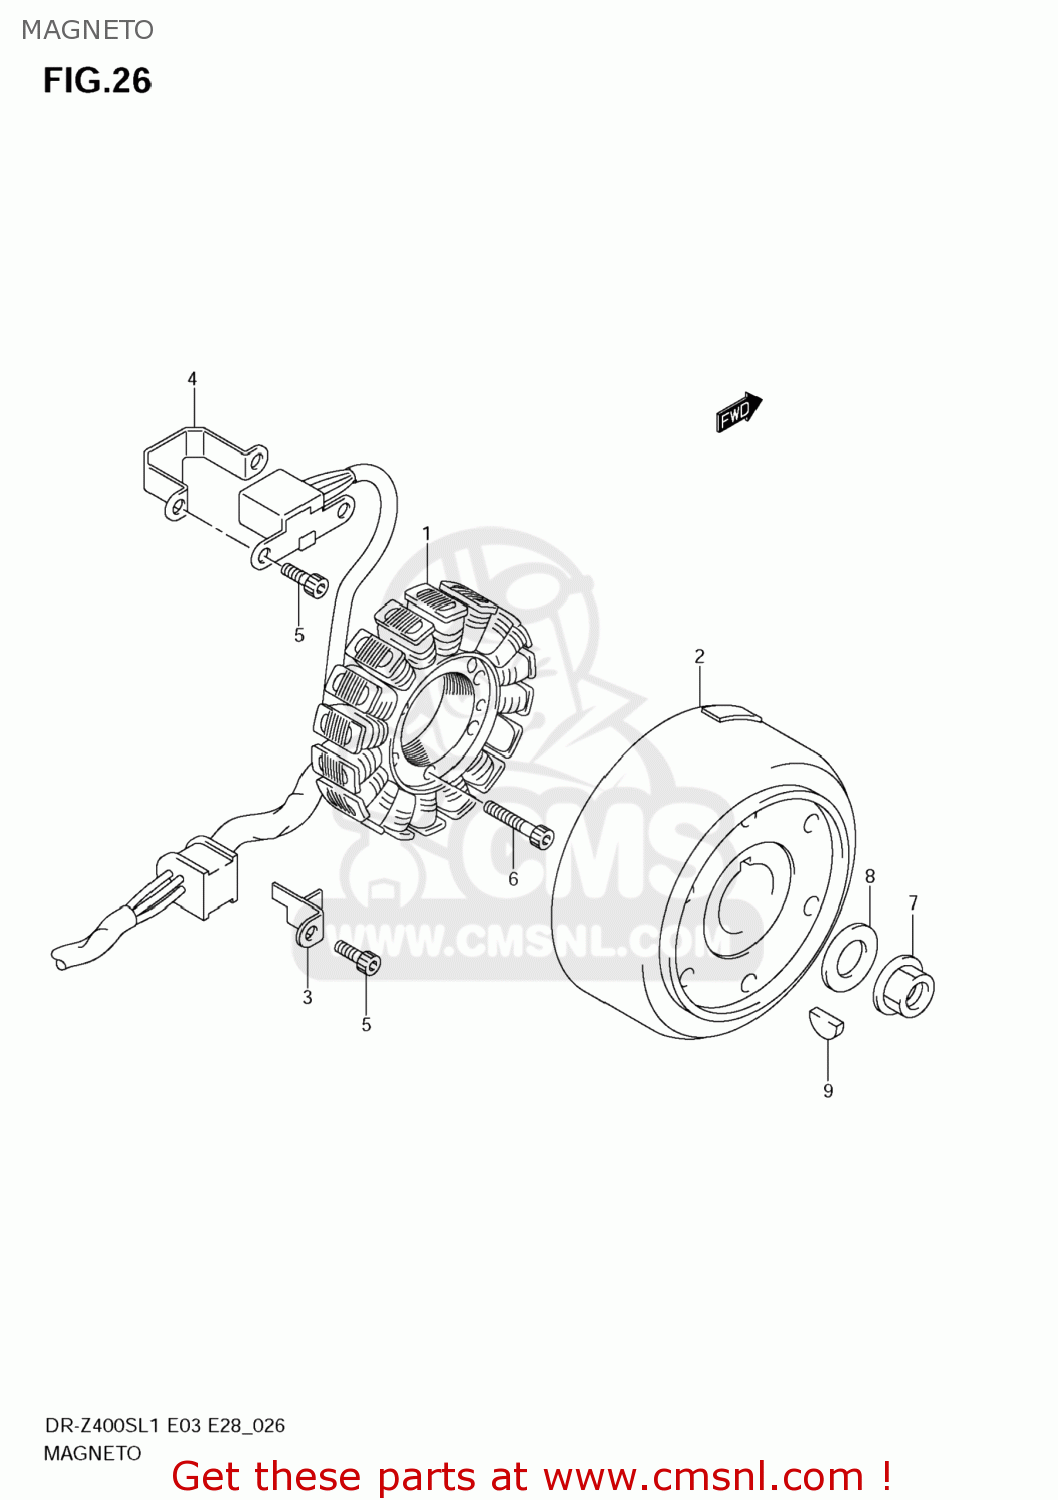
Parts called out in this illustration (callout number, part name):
1	STARTER ASSY
2	ROTOR ASSY
3	CLAMP,MAGNETO LEAD NO.1
4	CLAMP,MAGNETO LEAD WIRE
5	BOLT
6	BOLT
7	NUT
8	WASHER(12X27X2)
9	KEY
